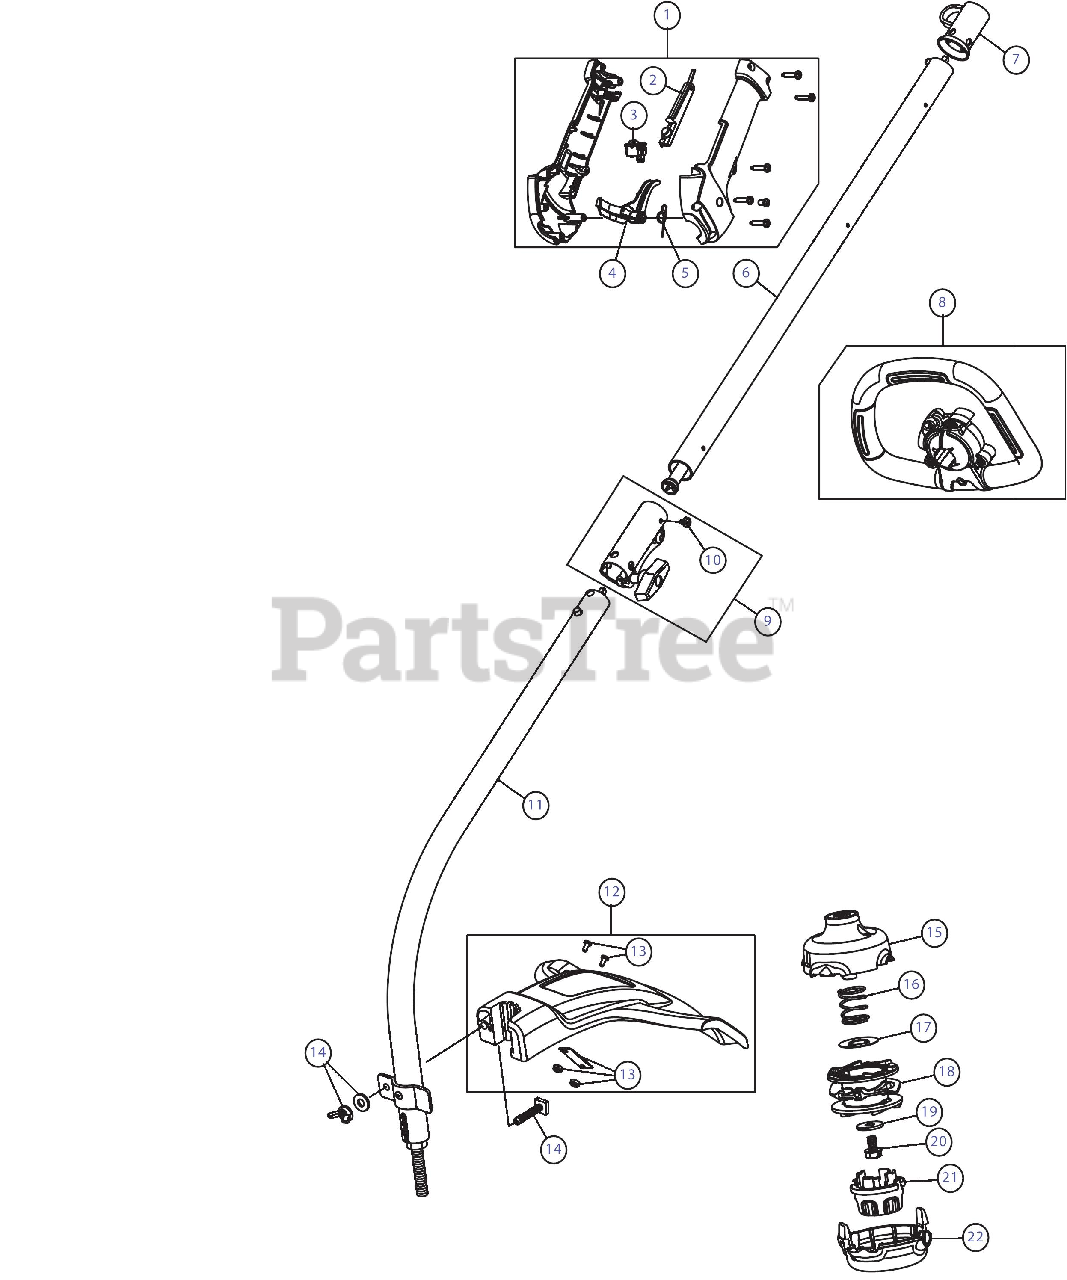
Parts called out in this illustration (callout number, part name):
1	Throttle Housing Assembly
2	Throttle Trigger Lock-Out
3	Throttle Switch Assembly
4	Throttle Trigger
5	Throttle Trigger Spring
6	Upper Shaft Housing Assembly
7	Hanger
8	Handle
9	Split Boom Coupler
10	Anti-Rotation Screw
11	Lower Drive Shaft Housing Assembly
12	Shield Assembly
13	Blade Assembly
14	Shield Mounting Hardware
15	2-N-1 Outer Spool
18	Inner Reel
19	Flat Washer
21	Bump Knob
22	Snap Cap
